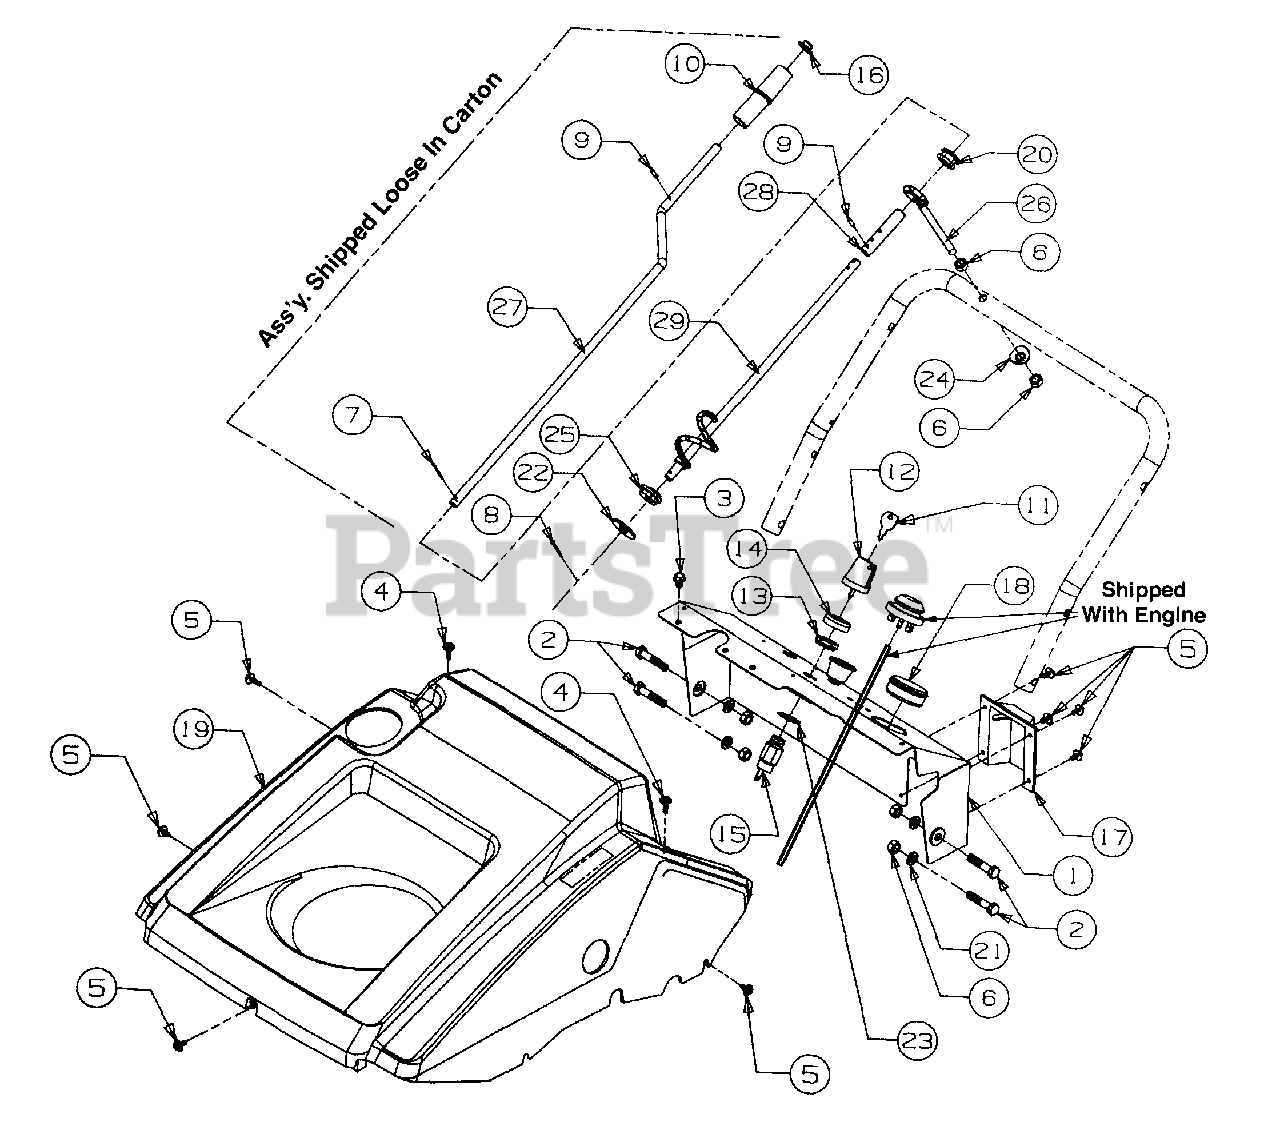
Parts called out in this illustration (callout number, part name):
3	Screw - Hex Washer
4	Screw - Hex
5	Screw - Hex
6	Nut - Hex
7	Pin - Cotter
8	Pin - Cotter
9	Pin - Roll
11	Key - Ignition
12	Key - Ignition with Logo
13	Nut - Ignition Switch
14	Cover - Ignition Switch
15	Switch - Key
16	Cap - Push
17	Cover - Choke
18	Plug - Insert
19	Shroud - Black
20	Grommet - Rubber
21	Washer - Lock
22	Washer - Flat
23	Washer - Lock Internal
24	Washer - Saddle
25	Bushing - Hex
26	Eyebolt - Chute Crank
28	Spacer
29	Crank - Chute Lower
